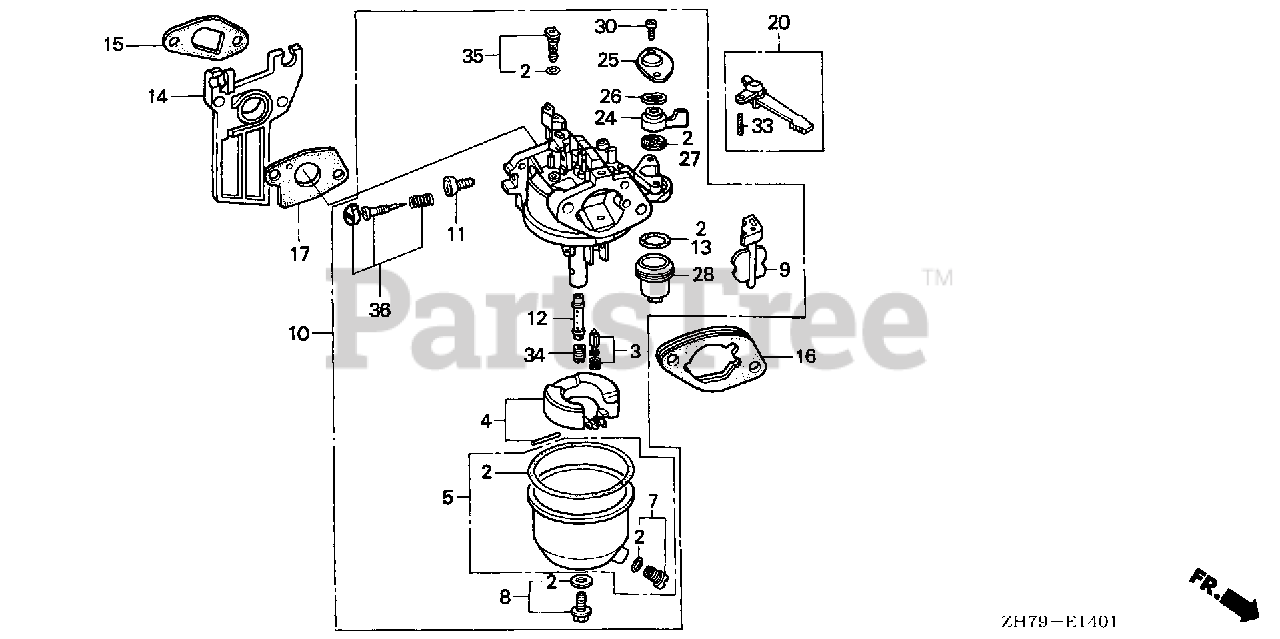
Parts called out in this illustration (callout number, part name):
2	GASKET SET
3	VALVE SET, FLOAT
4	FLOAT SET
5	CHAMBER SET, FLOAT
7	SCREW SET, DRAIN
8	SCREW SET B
9	CHOKE SET
10	CARBURETOR ASSY. (BE60B B)
11	SCREW, THROTTLE STOP
12	NOZZLE, MAIN
13	GASKET, FUEL STRAINER CUP
14	INSULATOR, CARBURETOR
15	GASKET, INSULATOR
16	SPACER, CARBURETOR
17	GASKET, CARBURETOR
20	LEVER, CHOKE (STD)
24	LEVER, VALVE
25	PLATE, LEVER SETTING
26	SPRING, VALVE LEVER
27	GASKET, VALVE
28	CUP, FUEL STRAINER
30	SCREW, PAN (3X6)
33	PIN, SPRING (2X12)
34	JET, MAIN (#55)
34	JET, MAIN (#58)
34	JET, MAIN (#60)
35	JET SET, PILOT (#35)
36	SCREW SET
